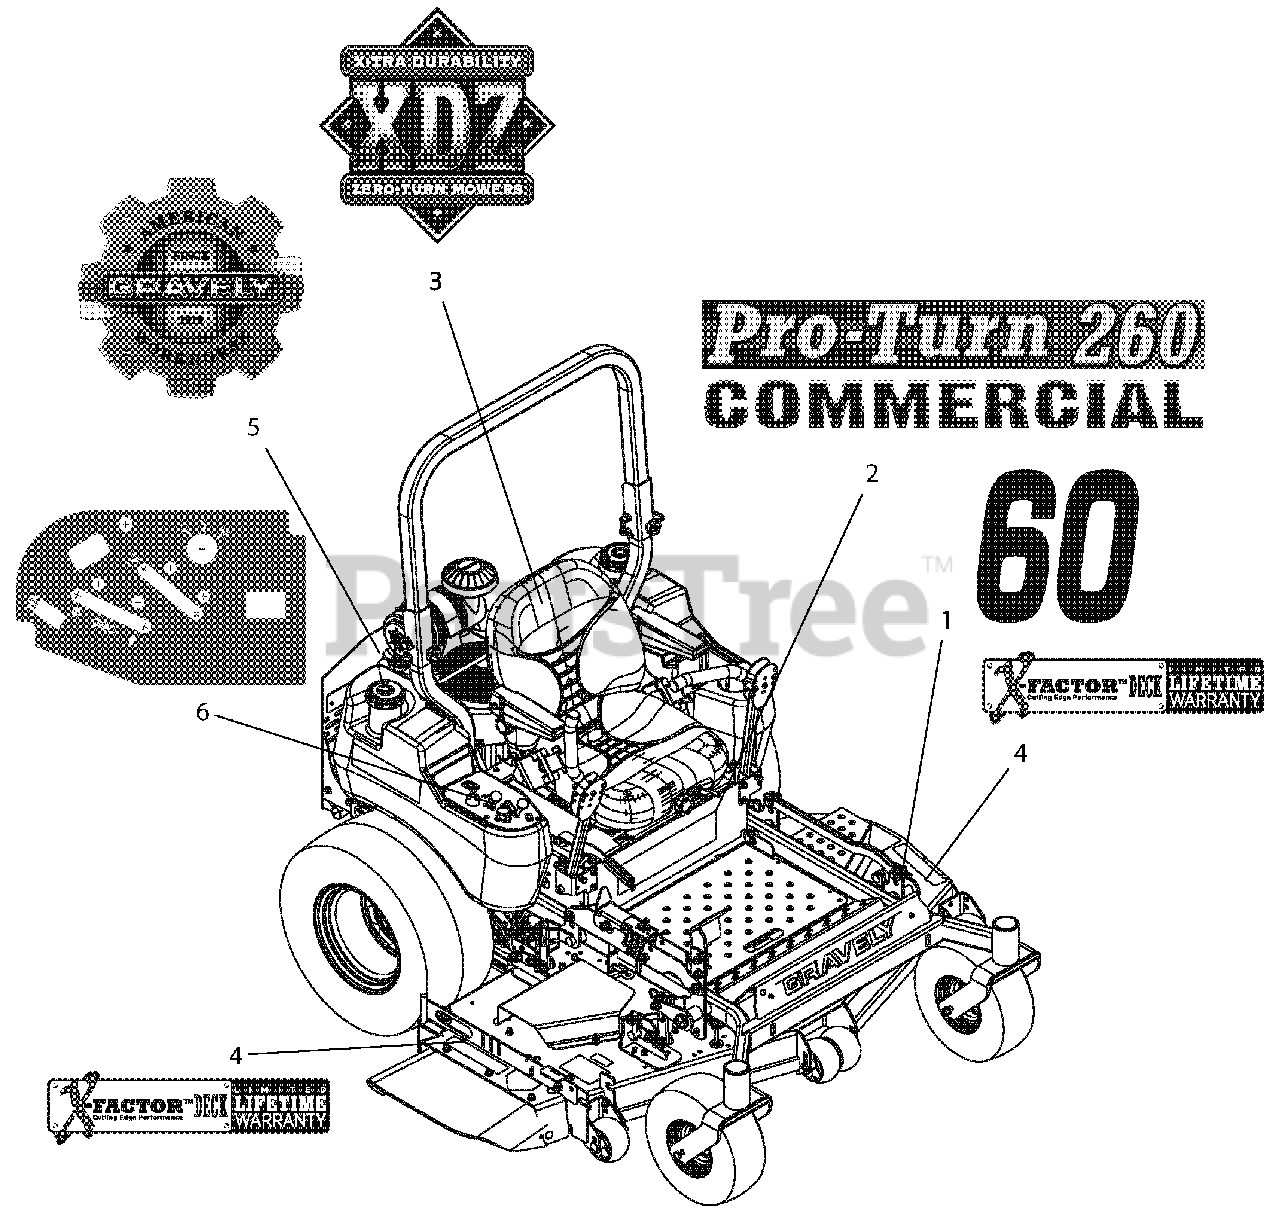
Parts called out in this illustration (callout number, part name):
1	DECAL, 60"
2	DECAL, PROTURN 260
3	DECAL, XDZ
4	DECAL, X-FACTOR DECK
5	DECAL, GRAVELY HERITAGE-LARGE
6	DECAL, CONTROL PANEL
